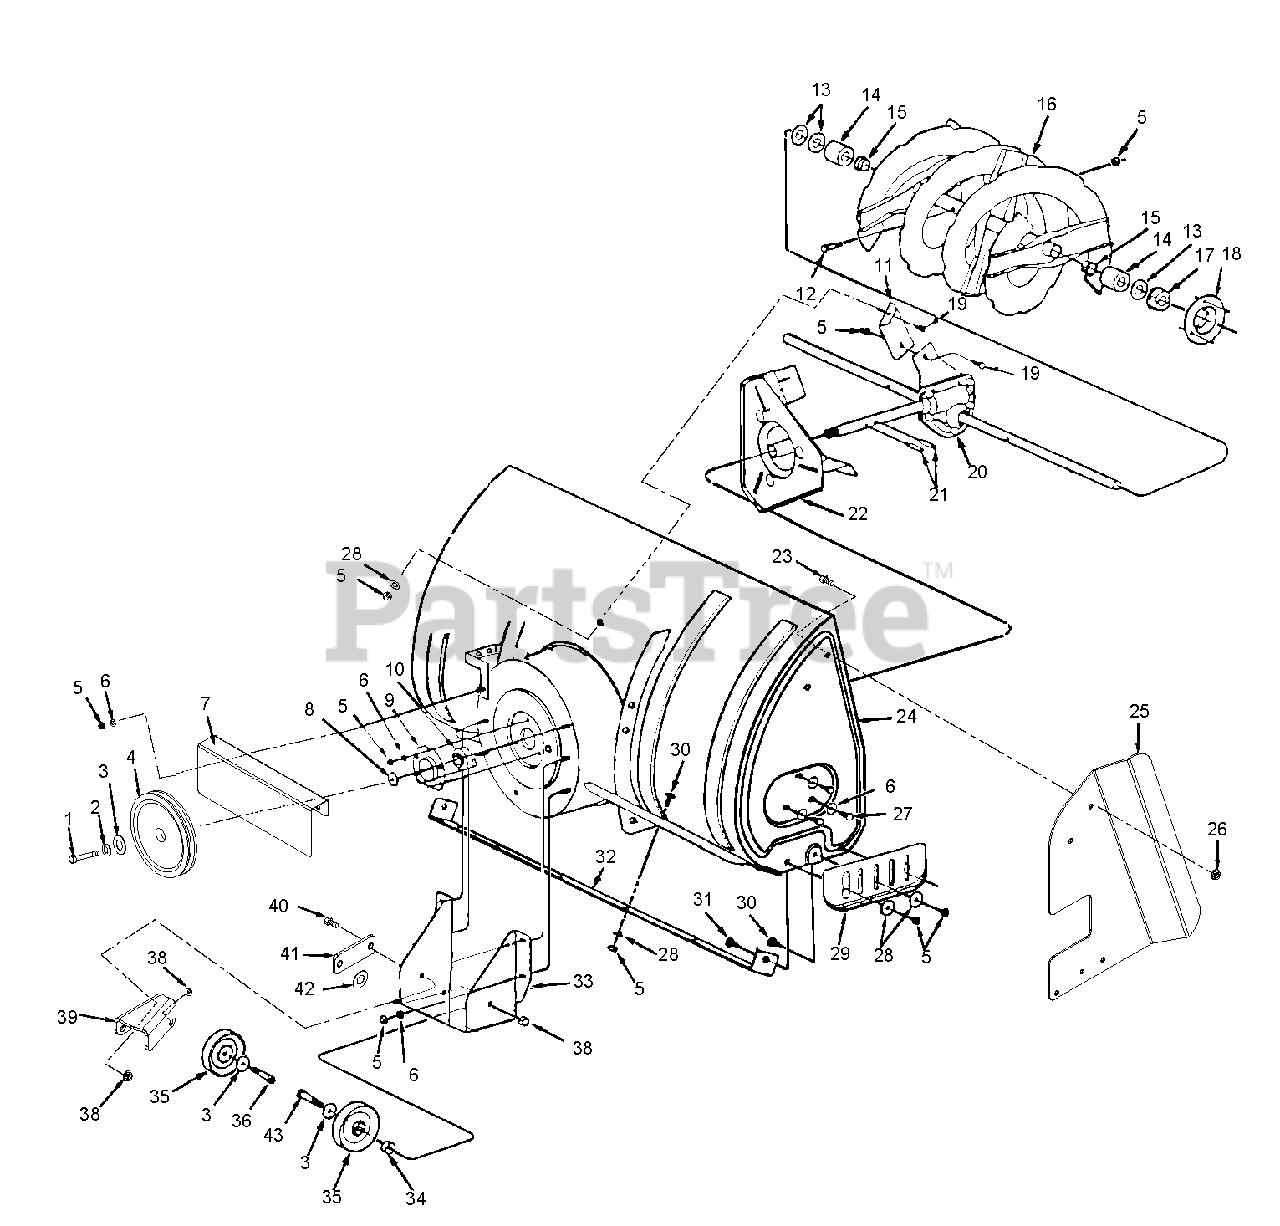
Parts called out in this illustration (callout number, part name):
1	Hex Bolt, 3/8-24 X 1
2	Lock Washer, 3/8
3	Washer
4	Pulley, V-Type
5	Hex Lock Nut, 5/16-18
6	Lock Washer 5/16
7	Finger Guard
8	Bushing
9	Housing, Bearing
10	Bearing, Ball
11	Bracket, Housing Brace
12	Bolt, Shear 5/16-18 x 1-1/2
13	Washer, .76 x 1.49 x .06
14	Spacer, .75 ID x 1.25 OD x .51
15	Bearing, Split, 3/4
16	Spiral Assembly, R.H.
17	Bearing Flange
18	Housing, Bearing
19	Hex Bolt, 5/16"-18 x 3/4"
20	Gear Assembly
21	Spiral Pin, 1/4 x 1-1/2"
22	Impeller Assembly
23	Bolt, Round Head Square Neck .31-18 x .75 Grade 5
24	Housing Assembly
25	Drift Cutter, Right Hand
26	Nut, Locking Top Flange .31-18
27	Bolt, Self-Tap 5/16 x 3/4"
28	Washer, 5/16
29	Skid Shoe
30	Carriage Bolt, 5/16-18 x 3/4
31	Carriage Bolt, 5/16-18 x 1
32	Scraper Plate
33	Bracket, Idler
35	Pulley, V-Type
36	Bolt, Hex .38-16 X 1.50 Grade 5
37	Spacer
38	Nut, Locking Top Flange .38-16
40	Bolt, Hex .38-16 X 1.00 Grade 5
41	Plate, Shim
42	Washer, Flat Steel .406 x 1.00 x.188
43	Bolt, Hex .38-16 X 2.00 Grade 5
NA	Spiral Assembly, L. H.
